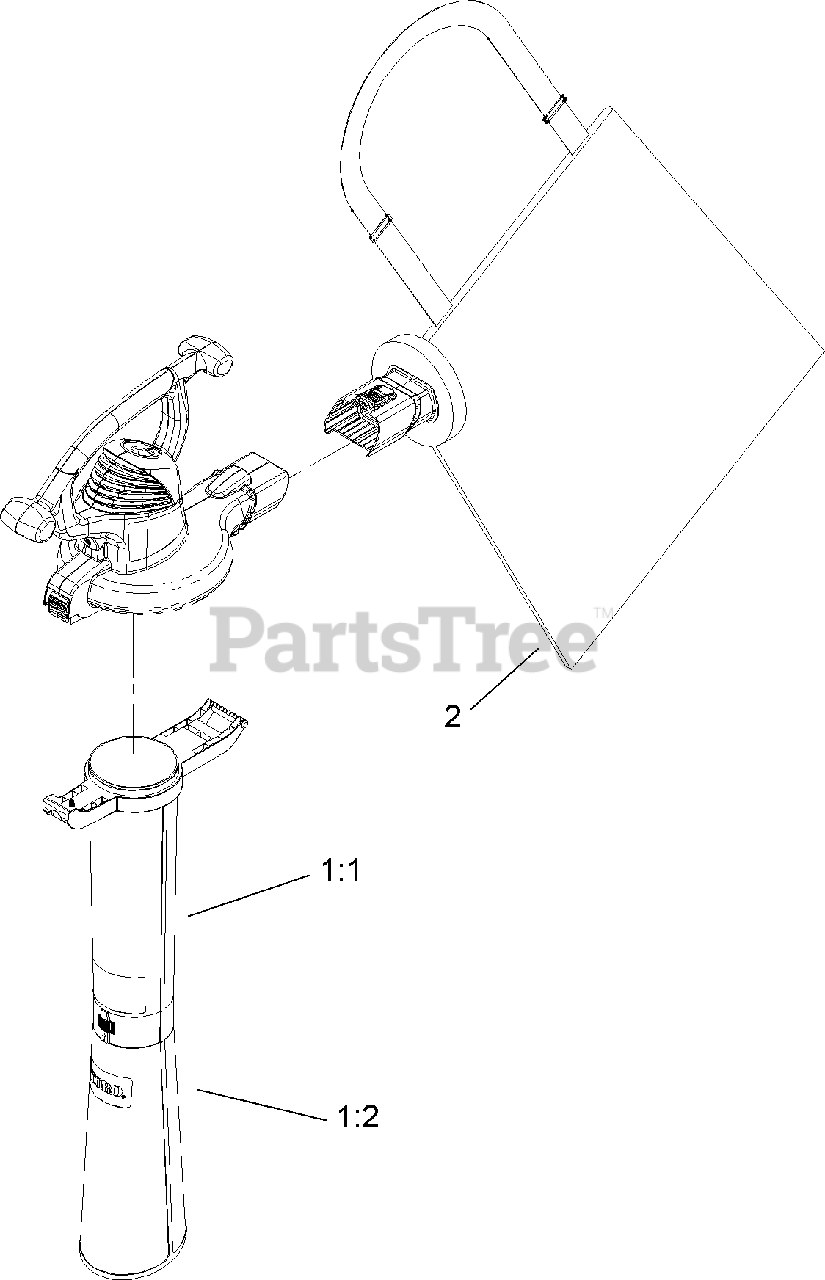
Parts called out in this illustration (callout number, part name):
1:1	TUBE-VAC, UPPER
1:2	TUBE-VAC, LOWER
2	BAG ASM
